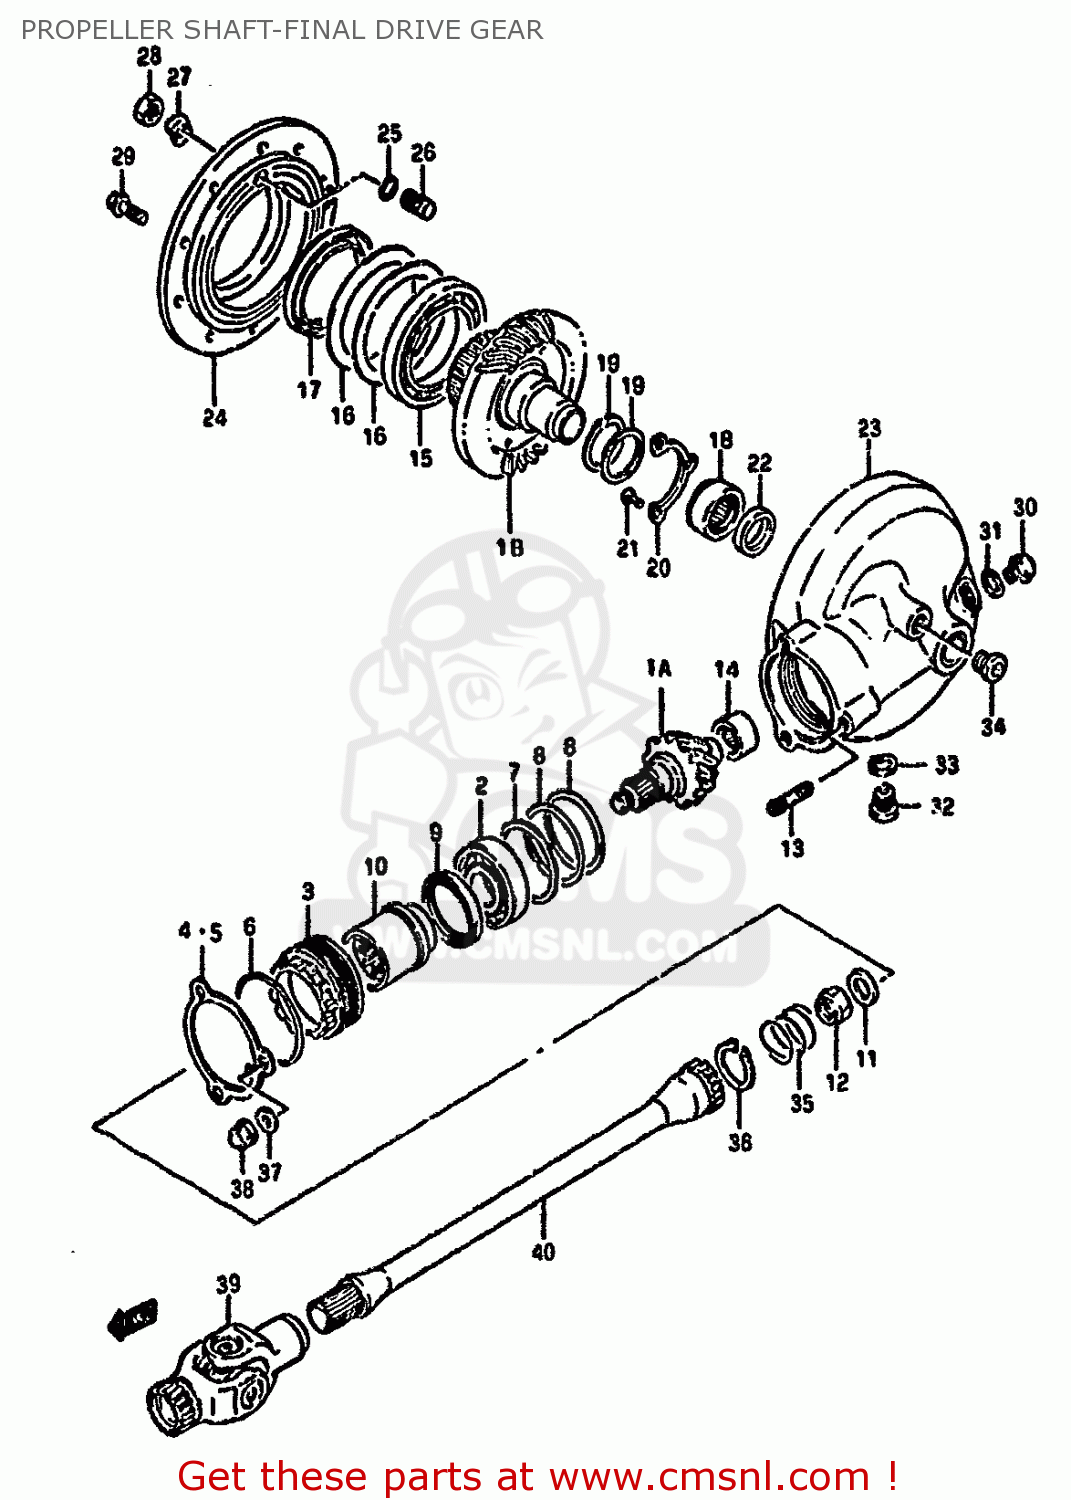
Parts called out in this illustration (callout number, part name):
1A	GEAR,FINAL DRIVE BEVEL
1B	GEAR,FINAL DRIVEN BEVEL
2	BEARING(28X68X18)
3	STOPPER,FINAL DRIVE BEARING
4	PLATE,BEARING STOPPER
5	PLATE,BEARING STOPPER
6	O RING(D:3.1,ID:63.9)
7	WASHER(54X68X1.5)
8	SHIM,FINAL DRIVE GEAR 62
9	SEAL,OIL
10	COUPLING,FINAL DRIVE GEAR
11	WASHER(16X29X4)
12	NUT
13	STUD 10X25
14	BEARING(20X34X18)
15	BEARING(70X110X13)
16	SHIM,DRIVEN GEAR BEARING
17	SEAL,OIL(70X96X16)
18	BEARING(35X48X23.7)
19	SHIM,FINAL DRIVEN GEAR
20	RETAINER,FINAL DRIVEN GEAR BRG
21	SCREW
22	SEAL,OIL(30X42X7)
23	CASE COMP,FINAL GEAR
24	CASE,FINAL GEAR BEARING
25	O RING(D:1.9,ID:9.8)
26	BOLT,FINAL DRIVEN GEAR THRUST
27	WASHER (54X68X1.5)
28	NUT
29	BOLT
30	PLUG(14X12)
31	GASKET(14X19.2X2) (NAS)
32	PLUG
33	GASKET(14X19.2X2) (NAS)
34	PLUG
35	SPRING
36	CIRCLIP
37	WASHER
38	NUT
39	YOKE COMP,UNIVERSAL JOINT
40	SHAFT,PROPELLER
